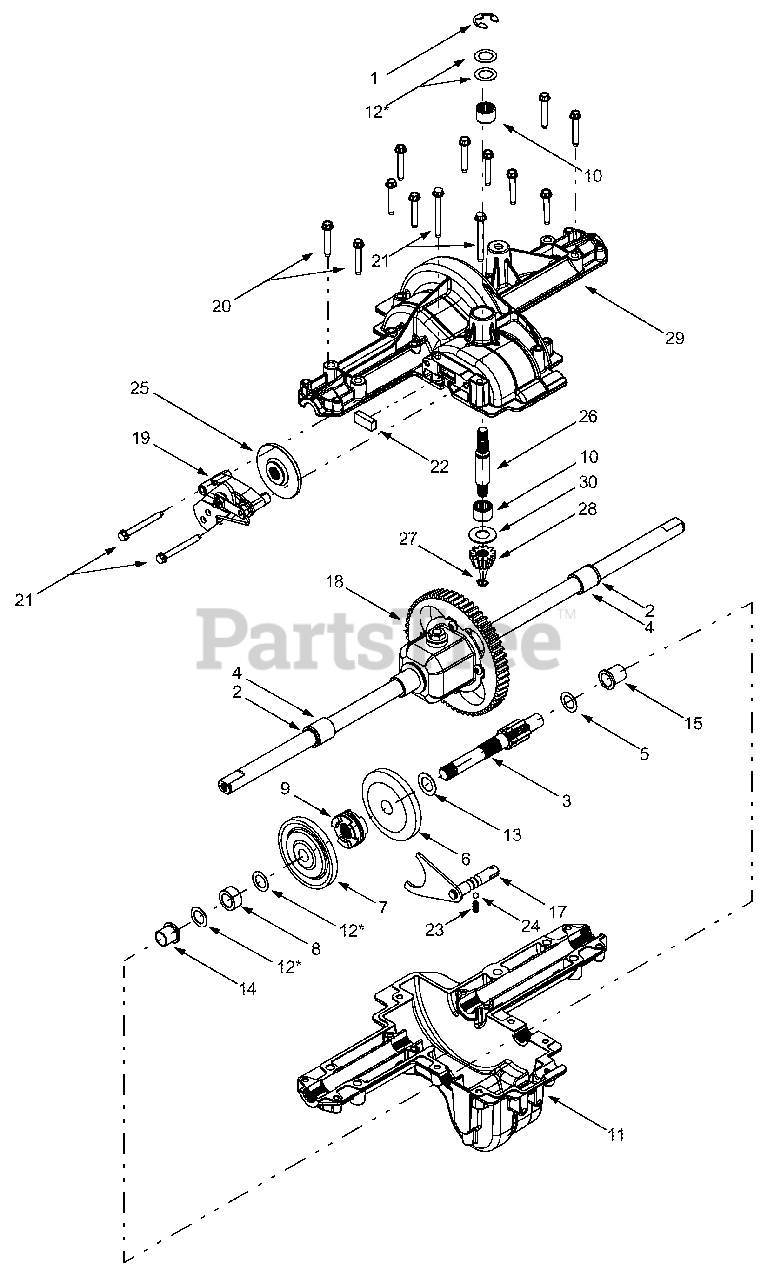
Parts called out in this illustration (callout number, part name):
1	E-ring, .75
2	Seal, .75 x 1.0 x .125
3	Drive Shaft
4	Sleeve Bearing, .75 x .1.0 x 1.0
5	Thrust Washer, 1.0 x .632 x .0
6	42-tooth Bevel Gear
7	42-tooth Bevel Gear
8	Spacer, .633 x 1.0 x .513
9	Clutch Collar
10	Needle Bearing, .625 x .875
11	Lower Housing
12	Flat Washer, 5/8 x 1.0 x .030 (12A)
12	Flat Washer, 5/8 x 1.0 x .040 (12B)
12	Flat Washer, 5/8 x 1.0 x .020 (12C)
13	Flat Washer, .70 x 1.125 x .031
14	Flange Bearing, 5/8 x 3/4 x 3/4
15	Flange Bearing, 5/8 x 3/4 x 15/16
16	Spacer, .635 x 1.0 x .27
17	Detent Shaft Assembly
18	Differential Assembly
19	Brake Assembly
20	Self-tapping Screw, 1/4-20 x 1.625
21	Self-tapping Screw, 1/4-20 x 2.375
22	Brake Pad
23	Compression Spring
24	Detent Ball
25	Brake Disc
26	Input Shaft
27	Retaining Ring, .437
28	14-tooth Bevel Pinion
28	12-tooth Bevel Pinion
29	Upper Housing
30	Thrust Washer, .635 x 1.25 x .042
